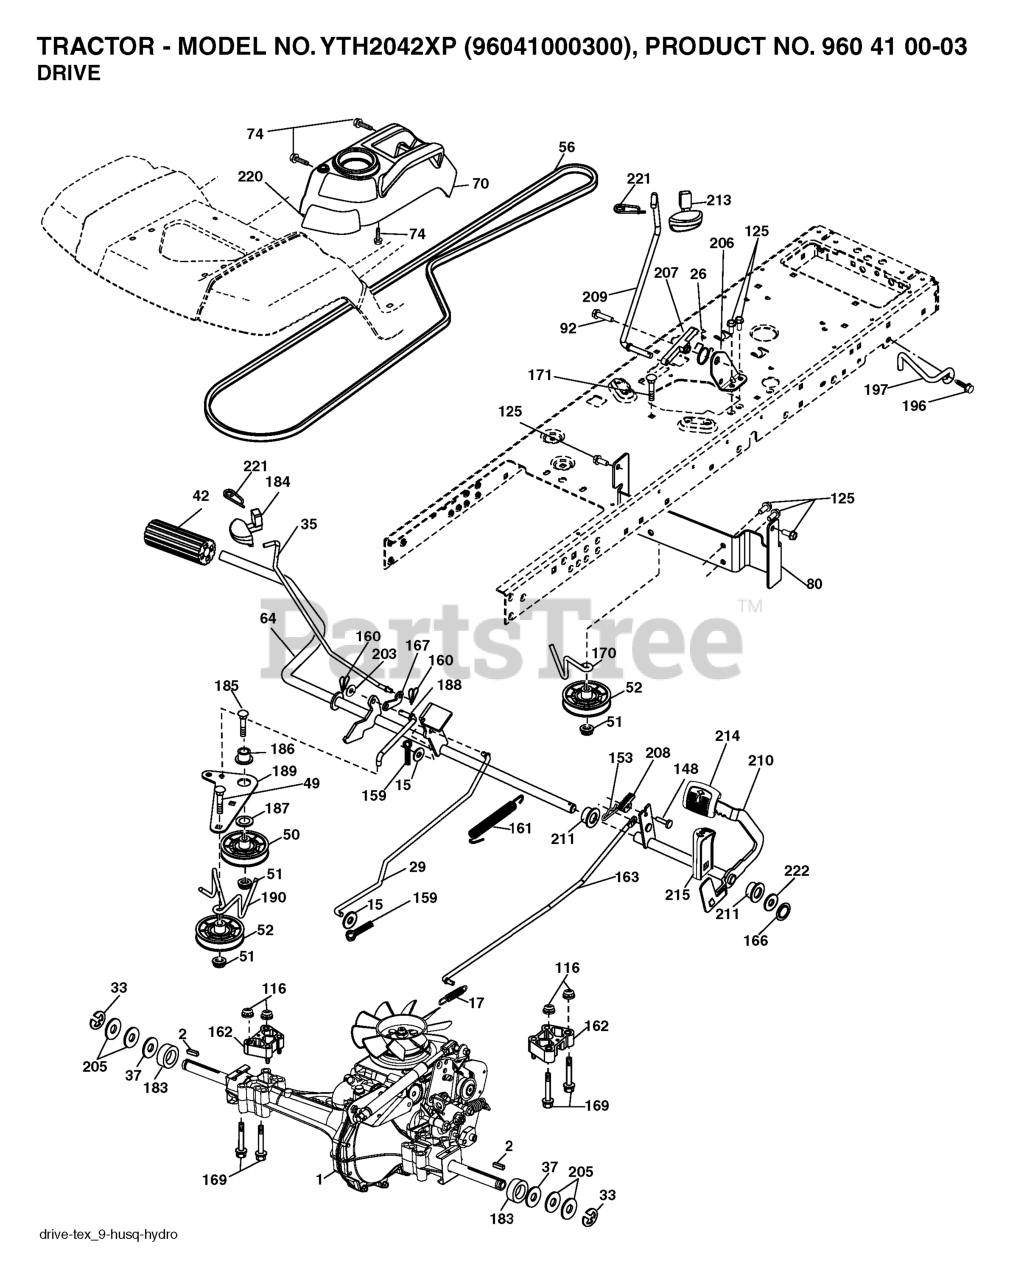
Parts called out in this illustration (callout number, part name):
2	SQUARE KEY
15	WASHER
17	SPRING.BRAKE.HG3000/3500
26	SPRING.RETURN.CRUISE
29	ROD.BRAKE.0610.PEDAL.CONTROL
35	ROD.BRAKE.PARKING.GT.H
42	PEDAL COVER T
50	IDLER.FLAT.910.OFFSET
51	NUT LOCK FLG 3/8-16 UNC
52	IDLER.V-GROOVE.910.OFFSET
64	SHAFT.ASM.PEDAL.BRK.CNTR
70	RP CONSOLE.ASM.PCH.W/TB
74	SCREW.HI-LO.CONSOLE
80	BRKT.STRP.TRQ.LT.HYD.C
92	BOLT
116	NUT LOCK HEX FLANGE 5/16-18
125	SCREW
143	Screw 5/16-18 x 1/2 Hex, Self Tapping 5/16-18 x 1/2
159	COTTER PIN
160	RETAINER CLIP
161	SPRING.RETURN.CLUTCH.2006
162	SPACER.TRANSAXLE.18&22
163	ROD.PEDAL.CONTROL.0510
166	NUT.PUSH.625.2006
167	LATCH.BRAKE.SPRING
169	BOLT.HEX.FLNG.5/16-18X3.75
170	KEEPER.V-IDLER.CENTER.
183	SPACER AXLE
184	HANDLE.PARKG.BRK.HUSQ X667
186	SPACER.RETAINER
187	WASHER 12/32X2X10GA
188	RP.LINK.CLUTCH.GROUND.DRIVE
189	BELLCRANK.GROUND.DRIVE.TEX.
190	KEEPER.BELLCRANK.DRIVE
196	SCREW 3/8-16X1
197	LINK.CLUTCH.ANIT-ROTAT
203	WASHER
206	BRKT.MOUNT.LATCH.CRUIS
207	LATCH.CONTROL.CRUISE
208	GEAR.SECTOR.CONTROL.CR
209	ROD.CONTROL.CRUISE.GT.
210	ROCKER.ASM.PEDAL.CONTR
211	BEARING.NYLON
213	KNOB.CONTROL.CRUSIE.HU
214	PEDAL.FORWARD.TEX.GT.4
215	PEDAL.REVERSE.TEX.GT.4
216	BRACKET.PULLEY.IDLER.W/TEX
218	BOLT.5/16-18X1-1/4 FULL.THREAD
219	SPACER.FENDER
220	REFLECTOR.RH.TEX GT
221	RETAINER.SPRING.CLIP.H
222	WASHER
